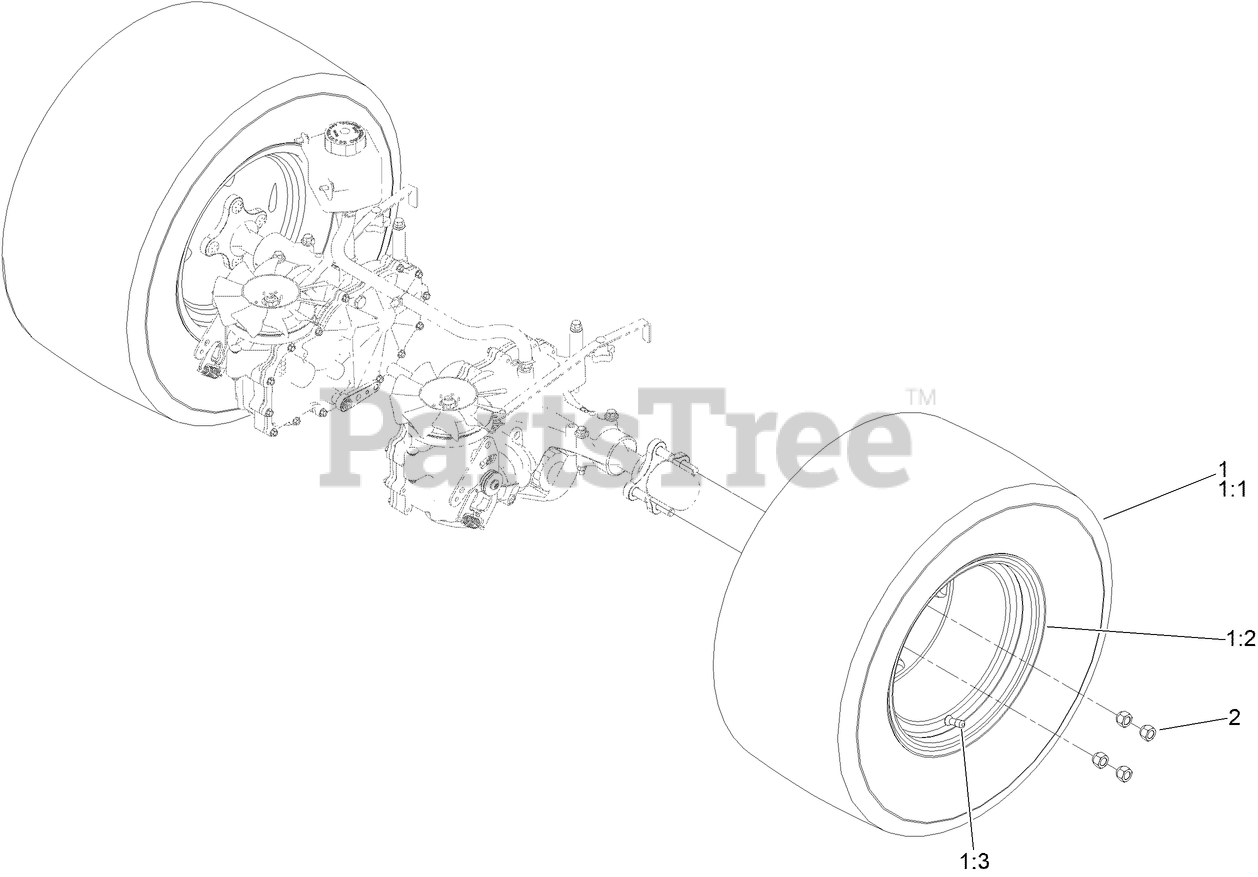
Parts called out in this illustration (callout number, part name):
1	WHEEL AND TIRE ASM
1:1	TIRE-VOODOO
2	NUT-LUG
